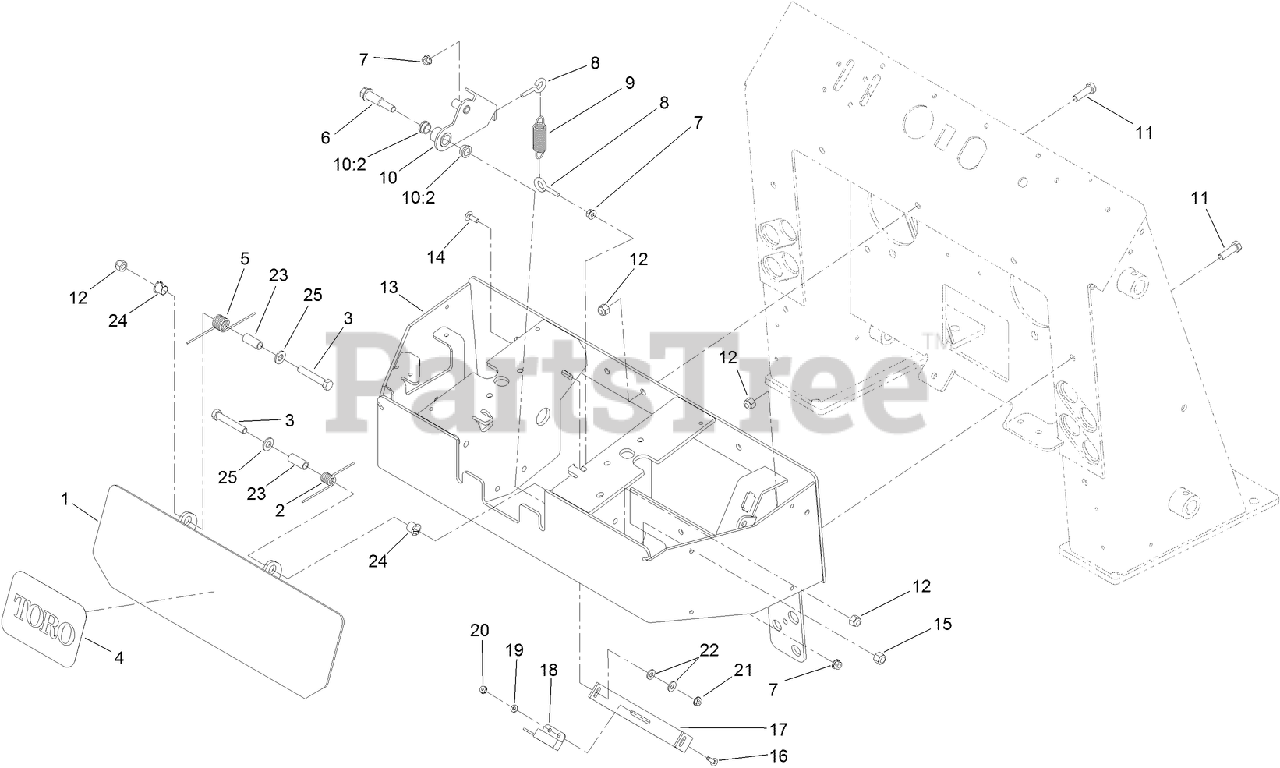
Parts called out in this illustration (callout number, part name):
1	PLATE-REVERSE
2	SPRING-TORSION, LH
3	SCREW-HH
5	SPRING-TORSION, RH
6	BOLT-SHOULDER
7	NUT-HHF
8	BOLT-EYE
9	SPRING-EXTENSION
10	NEUTRAL CENTERING LEVER ASM
10:2	BUSHING-FLANGE
11	SCREW-HH
12	NUT-LOCK, NI
13	PANEL-CONTROL
14	BOLT-CARR
15	NUT-LOCK
16	SCREW-CARR
17	PLATE-SWITCH
18	SWITCH-PROXIMITY
19	WASHER-FLAT
20	NUT-KEPS
21	NUT-KEPS
22	WASHER-FLAT
23	SPACER-SPRING
24	BUSHING-NYLINER
25	WASHER-FLAT
